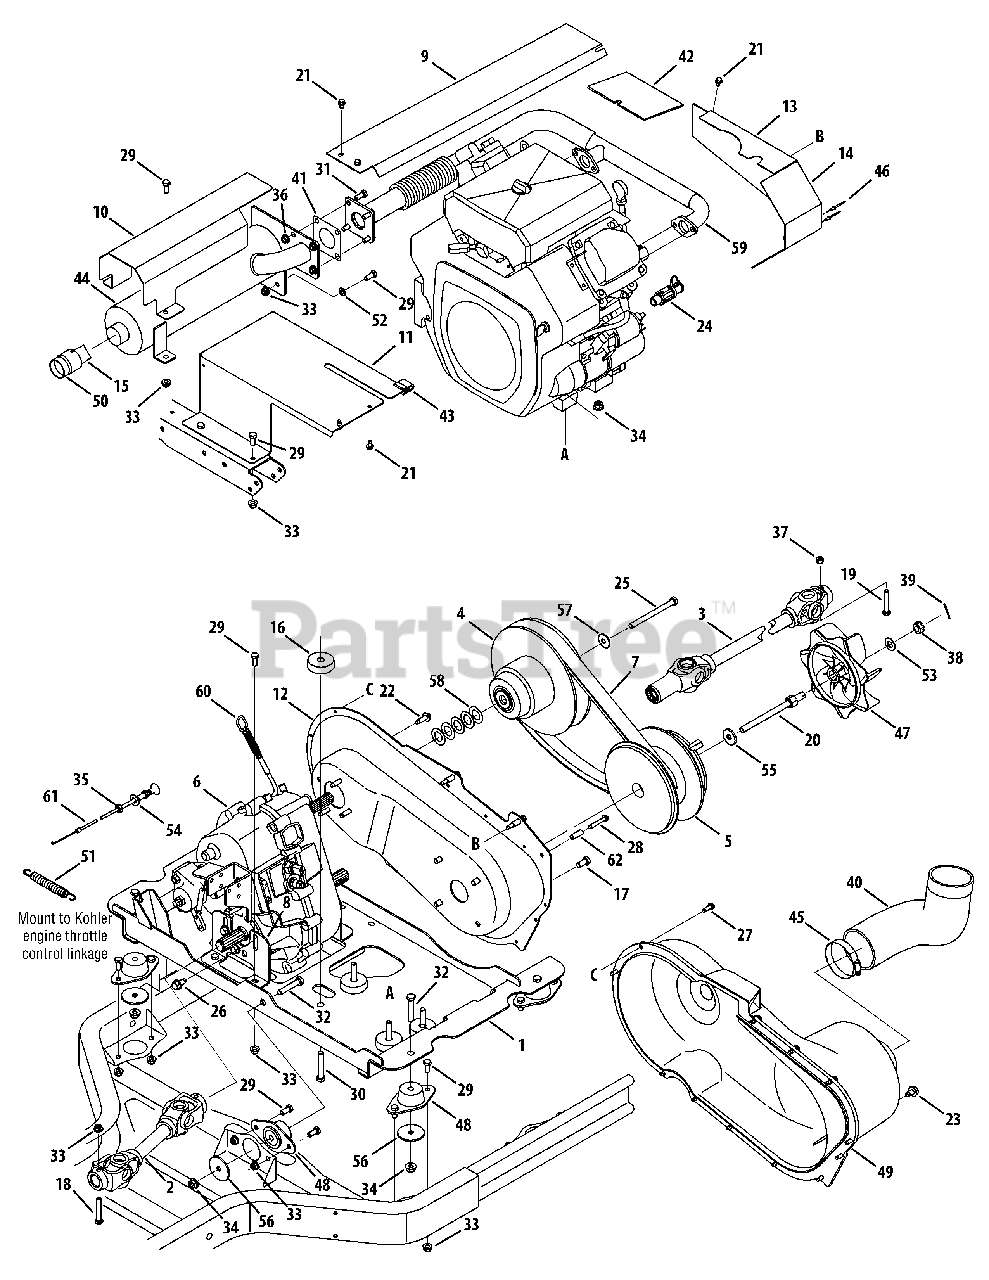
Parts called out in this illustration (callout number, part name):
2	Shaft Asm, Rr/prop
3	Shaft Asm, Frt/prop, Hilliard
4	Clutch Asm, Cvt, Driven
5	Clutch Asm, Cvt, Driver, Cover
6	Case Asm, Transfer
7	Belt, Cvt, 4x4
9	Cover, Heat, Sheild
10	Exhuast, Shield, Heat
13	Cover, Eng, Kohler
14	Cover, Engine, Rr, Kohler
16	Spacer, Engine, Kohl
17	Hhcs, 3/8-16, .75, Gr5, Std
18	Hhcs, 5/16-18, 2.00, Gr5, Patch
19	Hhcs, 5/16-18, 1.875, Gr5, Patch
20	Hhcs, 7/16-20, 5.00, Gr5, Special
21	Screw, Tt, 1/4-20, 0.500, Hxindwsh
22	Screw, Tt, 5/16-18, .875, Hxindwsh
23	Screw, B, 5/16-12, 0.500, Hxindwsh
24	Drain, Oil
25	Hhcs, 3/8-24, 4.50, Gr5, Std
25	Hhcs, 3/8-24, 3.50, Gr5, Std
26	Screw, Tt, 3/8-16, 0.750, Hxindwsh
27	Screw, Tt, 1/4-20, 0.750, Hxindwsh
28	Screw, Tt, 1/4-20, 1.625, Hxindwsh
29	Hhcs, 5/16-18, .75, Gr5, Std
30	Hhcs, 3/8-16, 2.25, Gr5, Std
31	Hhcs, 5/16-18, .875, Gr5, Std
32	Hhcs, 3/8-16, 2.00, Gr5, Std
33	Nut, Flglk, 5/16-18, Grf, Nylon
34	Nut, Flglk, 3/8-16, Grf, Nylon
35	Nut, Jam, 3/8-24, Gr5
36	Nut, Flglk, 5/16-18, Gr5, Sd Lk
37	Nut, Hexlk, 5/16-18, Grb, Ctrlk
38	Nut, Hex, 1/2-20, Gr5, Slot
39	Pin, Cot, 3/32, 1.0
40	Tube, Cvt, Intake
41	Gasket, Eng
42	Insl, Frame, Uv
43	Heat Baffle Seal
44	Muffler, Cat/khlr
45	Clamp, Hose, Adj.
46	Rivet, Pop, .125 Od, #42
47	Impeller, Blo
48	Mountt, Comprs, Eng, Hd
49	Cover, Cvt
50	Arrestor, Screwn, Spark
51	Spring Latch
52	Wash, Flat, .330 X .630 X .0635
53	Wash, Flat, .510 X 1.00 X .060
54	Wash, Flat, .406 X .875 X .059
55	Wash, Flat, .450x1.250x.164, Ht
56	Wash, Flat, .38 X 2.00 X .12
57	Wash, Bell, .396 X 1.140 X .095
58	Wash, Fl, .793x1.368 X.025, Ht
59	Pipe, Exh, Kohl
59	Pipe, Exh, Kohl, EFI
60	Cable Kit, Throttle, Kohler
61	Cable, Control Choke, Kohler
62	Spacer, .260id X .375od X 1.0l
